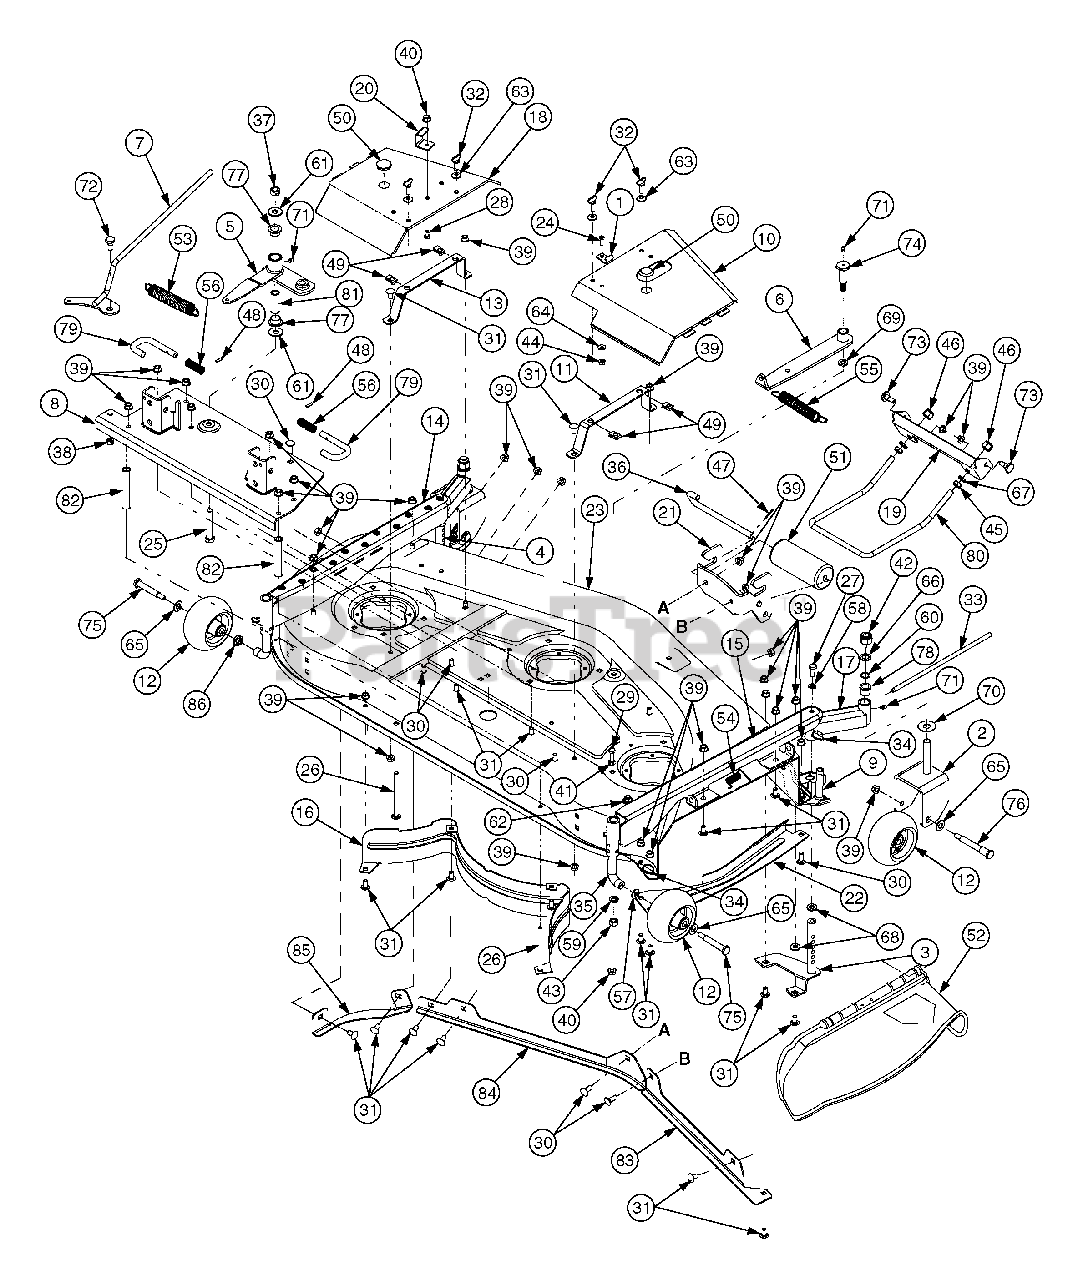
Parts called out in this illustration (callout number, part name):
1	Bracket, Hook Retainer
3	Spindle, Adjustment RH
4	Spindle, Adjustment LH
5	Bracket, Idler
24	Screw, Hex Cap 1/4-20 x .62 GR5
25	Screw, Hex Cap, 1/2-20 x 3.0 GR8
26	Carriage, Bolt 3/8-16 x 5.0 GR5
27	Screw, Hex Cap, 3/8-16 x .88 GR5
28	Screw, Hex Cap, 5/16-18 x .5 GR5
29	Screw, Hex Cap, 5/16-18 x 2.25 GR5
30	Carriage, Bolt 3/8-16 x 1.0
31	Carriage, Bolt 3/8-16 x .75
32	Screw, Thumb Adjust 5/16-18 x 1
33	Pin, Hinged .375 x 14.06
34	Pin, Clevis w/Ball Detent
35	Axle, Castor
36	Pin, Roller 1/2 x 7.31
37	Nut, Hex Lock, 1/2-20 GRA
38	Nut, Hex Lock, 3/8-16 GRA
39	Nut, Flange Lock 3/8-16
40	Nut, Flange Lock, 5/16-18 GR5
41	Nut, Hex , 5/16-18 GR5
42	Nut, Hex Lock 5/8-11
43	Nut, Hex, 7/16-14 GR2
44	Nut, Hex Flange Lock 1/4-20
45	Nut, Hex Jam, 1/2-13 GR5
46	Nut, Hex Insert Lock, 1/2-13 GR8
47	Pin, Cotter 3/32 x 1.25
48	Pin, Spirol
49	Nut, "U" 5/16-18
50	Plug, Button
51	Roller, Front
52	Deflector, Chute
53	Spring, Extension
54	Spring, Torsion
55	Spring, Extension
56	Spring, Compression
57	Washer, Bell, .375 x .87 x .063
58	Washer, Lock 3/8" I.D.
59	Washer, Lock 7/16" I.D.
60	Washer, Wave, .625 x .885 x .015
61	Washer, Flat, .5 x 1.25 x .10
62	Washer, Flat, .535 x .93 x .09
63	Washer, Bell .34" I.D.
64	Washer, Bell .265 x .75 x .062
65	Washer, Flat, .51 x 1.0 x .06
66	Washer, Flat, .625 x 1.0 x .067
67	Washer, Lock, 1/2
68	Washer, Flat, .406 x .875 x .105
69	Washer, Flat, .469 x .875 x .105
70	Washer, Flat, 1.595 x .635 x .062 HT
71	Fitting, Lube, 3/16 Drive
72	Screw, Shoulder, .498 x .34: 3/8-16
73	Screw, Shoulder, .5 x .434: 3/8-16
74	Screw, Shoulder, .68 x 1.59
75	Screw, Shoulder, .5 x 2.5
76	Screw, Step Shoulder, 5/8-1/2 x 3.41
77	Bearing, Flange, 3/4 x .52
78	Bearing, Flange, .63 ID
79	Pin, Mower Support
80	Rod, Deck Hanger
81	Spacer, .5 x .75 x 2.07" Lg.
82	Spacer, .405" x .75 x 3.875" Lg.
86	Spacer, Shoulder
